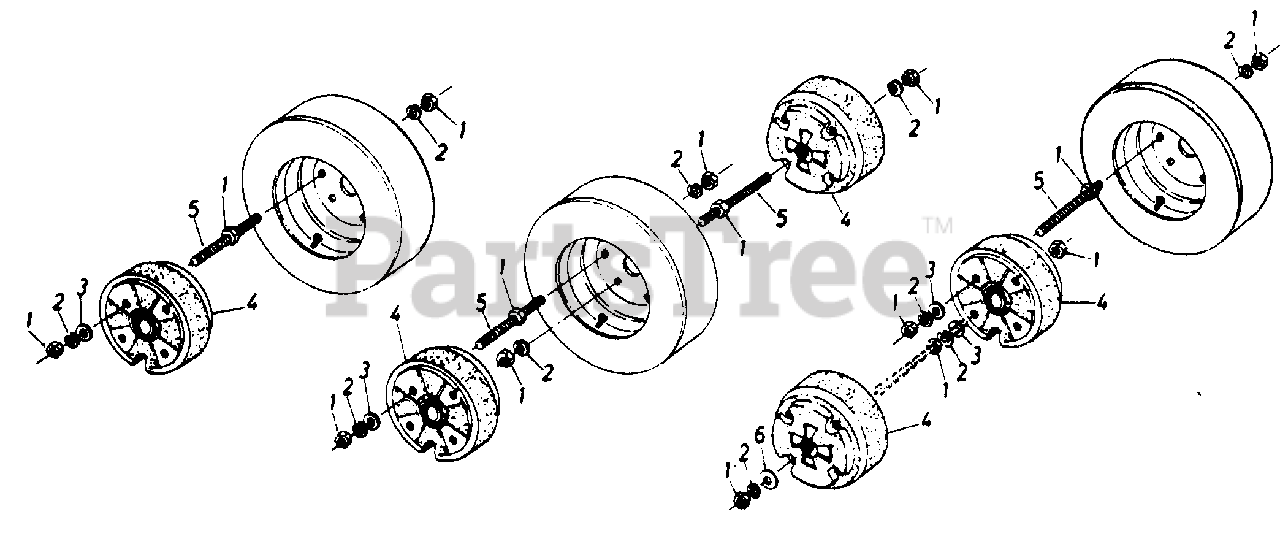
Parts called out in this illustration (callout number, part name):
1	Hex Nut 1/2-13 Thd.
2	Lock Washer 1/2 I.D.
3	FlatWasher .53 I.D. x .93 O.D.
4	Wheel Weight
5	Rod Threaded 1/2-13 x 9.50 Lg.
6	Fl.-Washer .50 I.D. x 2.00 O.D.
